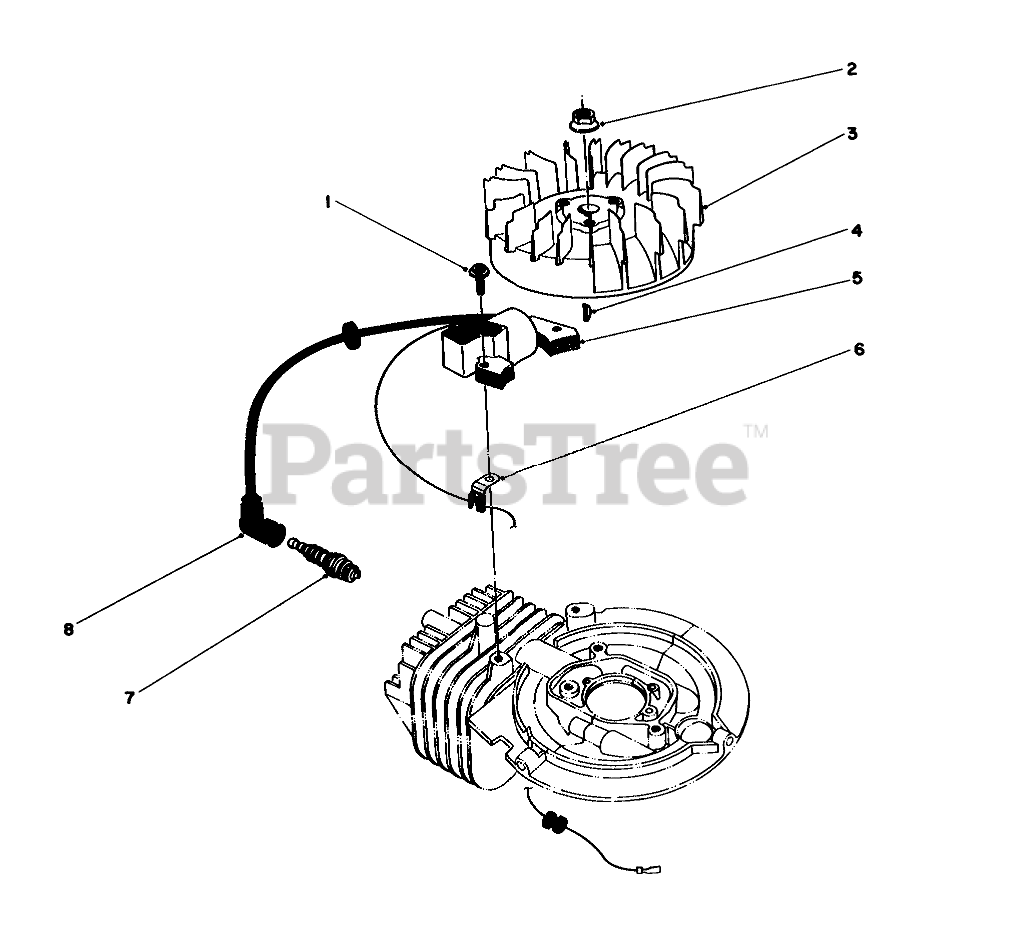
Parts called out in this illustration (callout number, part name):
1	Allenhead
3	FLYWHEEL
4	Key-Flywheel
5	Coil/Ignition Assembly
6	CLAMP
7	Sparkplug
8	CAP-SPARKPLUG
